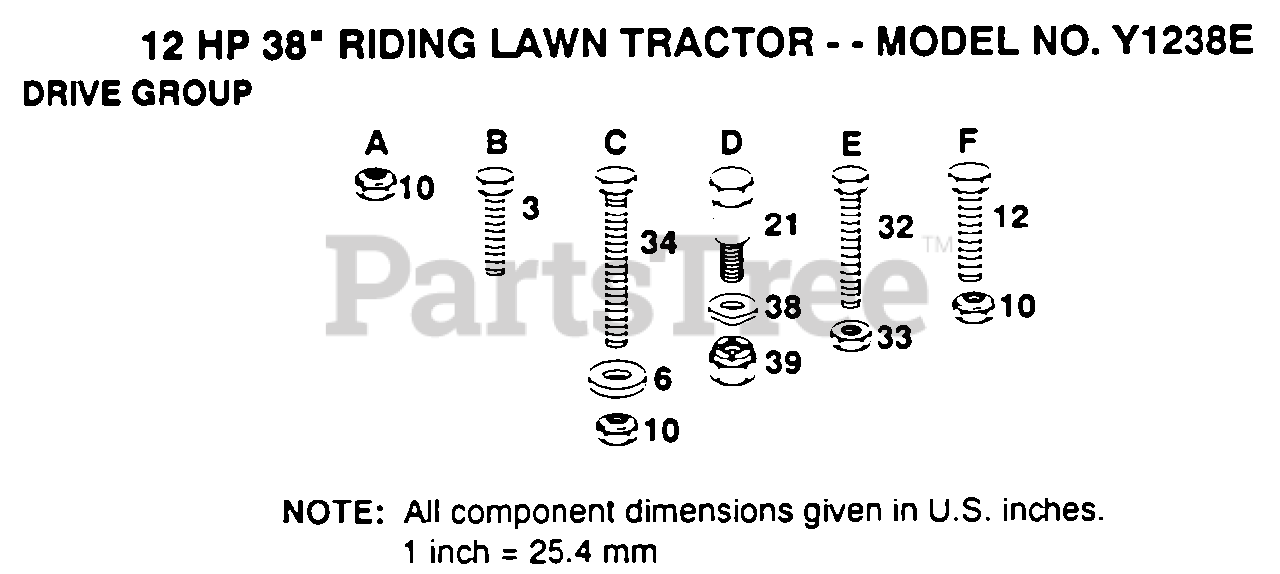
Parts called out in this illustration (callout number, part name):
3	SCREW
6	WASHER
21	"BOLT, SHOULDER LT"
32	BOLT
34	BOLT
38	WASHER T
39	NUT SPECIAL T
